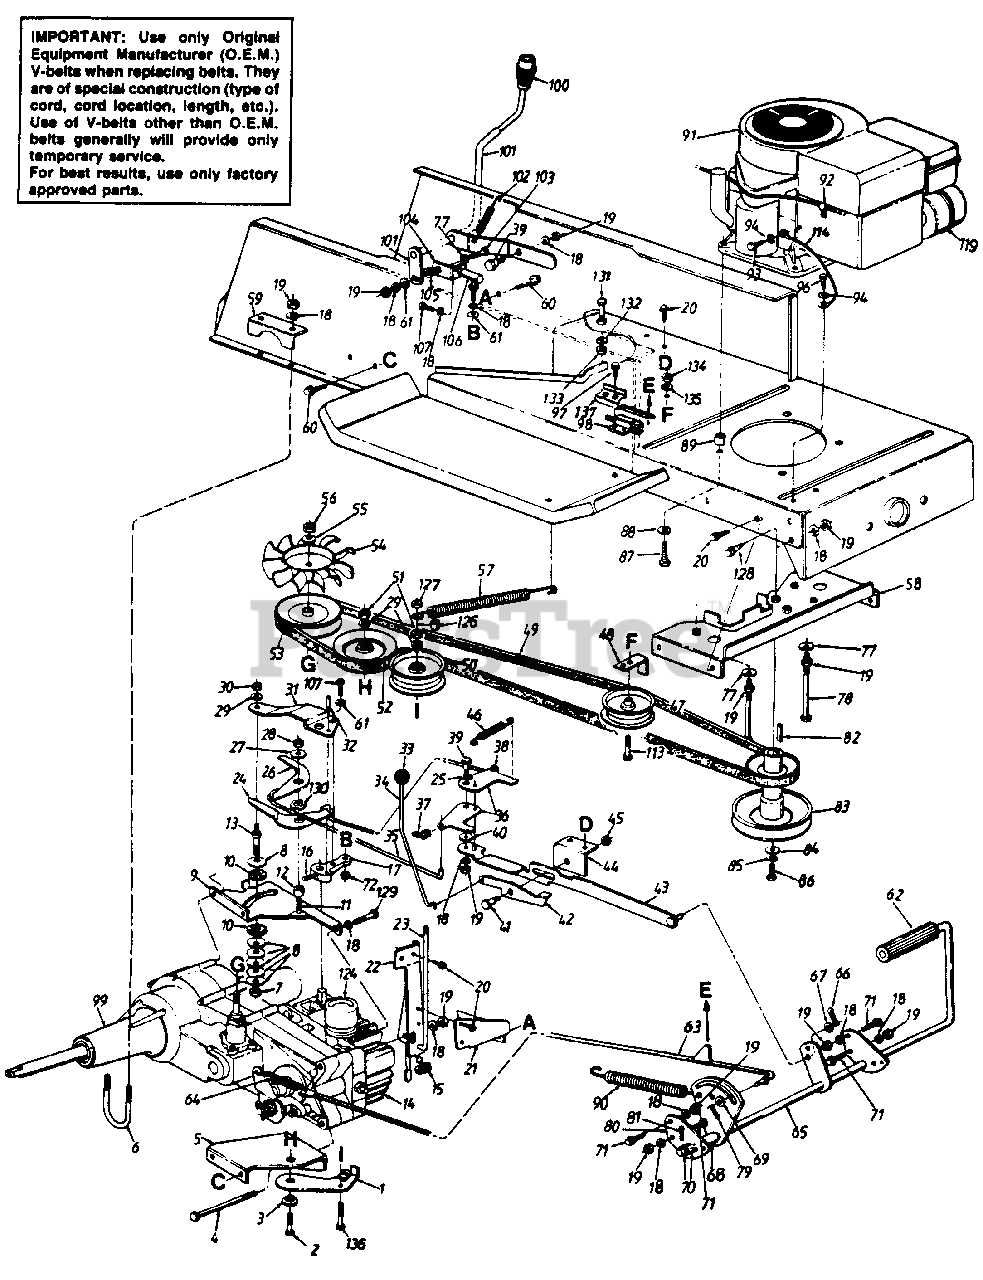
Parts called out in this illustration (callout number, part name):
1	Idler Bracket
2	Hex Bolt 3/8-16 x 2 0n Lg.
3	Shld. Spacer.625" l.D.
4	Hex Bolt 5/16-18 x 4.5" Lg. (Gr. 5)
5	Idler Plate
6	U-Bolt 5/16-18 x 1.75" Lg.
7	Hex L-Nut 3/8-24 Thd.
8	Bell-Wash. .40" I.D. x 1.13"
9	Mounting Bracket
10	Friction Washer
11	Rib Neck Bolt 5/16-24 x .84" Lg.
14	Hrostatic Pump
15	Rubber Washer .331' I.D.
17	Pintle Shift Lever
18	L-Wash. 5/16 I.D.
19	Hex Nut 5/16-18 Thd.
20	Hex TT-Tap Scr. 20 x .5n
21	Reinforcement Plate
22	Transmission Torque Brkt.
23	Release Valve Rod
24	Reverse Arm
25	Spring Washer .625n l.D.
26	Forward Arm
27	Fl-Wash. .344' I.D. x 1.0n
28	Hex Cent. L-Nut 5/16-24 Thd.
29	L-Wash. 3/8n l.D.
30	Hex Nut 3/8-24 Thd.
31	Pintle Arm Ext. Plate
32	Roll Pin 1/4n Dia. x .75" Lg.
35	Connection Rod
36	Balancer Bracket
37	Rod End Clevis Clips-R.H.
38	Rod End Clevis Clips-L.H.
39	Shld. Bolt .437n Dia. x .268n
40	Fl-Wash. .344" I.D. x 1.12n
41	Shld. Bolt .437" Dia. x .35n
42	Lock-Up Bracket
43	Neutral Return Brkt. Ass'y.
45	Hex Cent. L-Nut 5/16 18 Thd.
46	Ext. Spring 2.5" Lg.
47	Idler Pulley 3.06n O.D.
51	Hex Nut 3/8-16 Thd.
52	Idler Pulley 4.0n O.D.
53	Transmission Pulley
55	Bell-Wash. .569n l.D. x 1.125n
56	Hex Jam Nut 9/16-18 Thd.
57	Extension Spring
58	Belt-Guard Brkt. Ass'y.
59	Bracket
60	Hex Wash. Hd. B-Tap Scr. 5/16-18 x .5n Lg.
61	Flat Tooth Washer 5/16" I.D.
62	Foot Pad
63	Brake Rod Ass'y.
64	Ext. Spring 3.67" Lg.
65	Clutch Brake Pedal Ass'y.
66	Intern. Cotter Pin 5/16" Dia.
67	Fl-Wash. .385" l.D. x .62"
68	Spacer.63" I.D.
69	Fl-Wash. .385" I.D. x .62"
70	Fl-Wash. .635" l.D. x l.On
71	Hex Wash. TT-Tap Scr. 5/16-18 x 7/8" Lg.
72	Hex Nut 5/16-24 Thd.
77	Bell-Wash. .345" I.D. x .88"
78	Hex Bolt 5/16-18 x 4.0" Lg.
79	Cotter 3/32" Dia. x .75" Lg.
80	Pedal Brkt.
81	Cotter Pin 3/32" Dia. x 1.0" Lg.
82	Sq.-Key l/4" x 2.0"
83	Engine Pulley
84	Fl-Wash. 7/16" l.D. x 1.25'
85	LWash. 7/16" l.D.
86	Hex Bolt 7/16-20 x l.5" Lg.
87	Hex TT-Tap Scr. 3/8-16 x 1.5
88	Fl-Wash. .406" l.D. x 1.25"
89	Spacer .88n I.D. x 1.25' O.D.
90	Extension Spring 6.11" Lg.
91	Engine
93	Truss Mach. Scr. 5/16-18 x .75'
94	External L-Wash. 5/16" I.D.
96	Hex AB-Tap Scr. 5/16 x .75"
97	Truss B-Tap Scr. #10 x .5"
98	Safety Switch
101	Speed Selector Lever Ass'y.
102	Ext. Spring 2.75n Lg.
103	Hex Bolt 5/16-18 x 1.25" Lg.
104	Connection Brkt.
105	Shoulder Nut
106	Ball Joint 5/16-24 Thd.
107	Hex Bolt 5/16-24 x .75n Lg.
113	Hex Bolt 3/8-24 x l.75n Lg.
114	Ground Wire 7.25n Lg.
124	Reservoir
126	Spacer .375n l.D. x .503n
127	Hex Jam Nut 3/8-16 Thd.
128	Hex TT-Tap Scr. 5/16-18 x .62"
129	Hex Bolt 5/16-18 x 43/4n Lg.
130	Spring Washer .625" l.D.
131	Hex Bolt 1/4-20 x 1.25" Lg.
132	L-Wash. 1/4" I.D.
133	Hex Nut 1/4-20 Thd.
134	Hex L-Nut 3/8-24 Thd.
135	Fl-Wash. .385" l.D. x .87"
136	Hex Bolt 3/8-16 x 2.5" Lg.
137	Switch Plate
